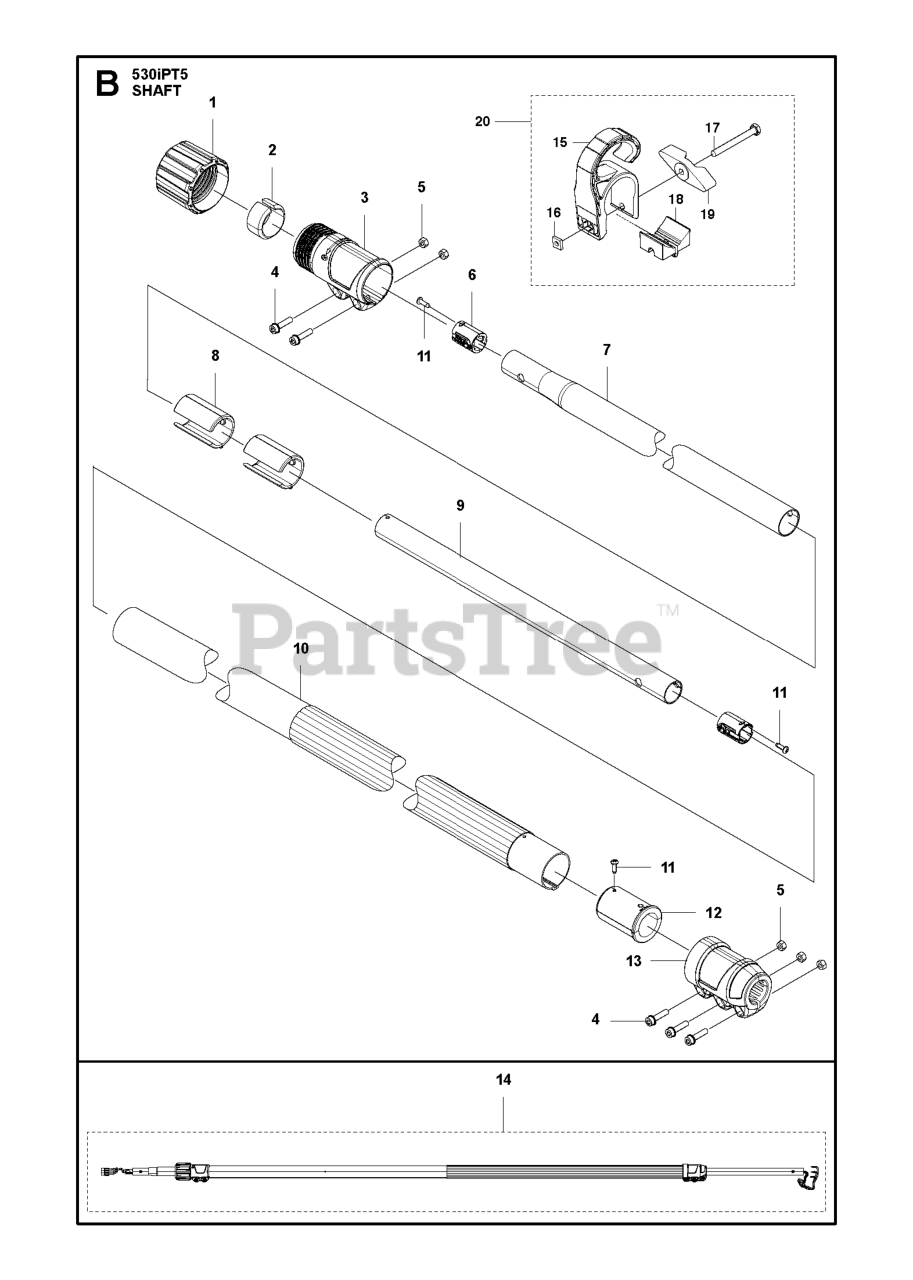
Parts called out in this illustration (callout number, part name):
3	CLAMPING SLEEVE
6	SPACER CABLELOCK
7	TUBE UPPER
8	GUIDE BUSHING
9	TUBE LOWER
10	TUBE ASSY LOWER
11	SCREW
13	CLAMPING SLEEVE
14	TUBE ASSY TELESCOPIC
17	SCREW M6X55
18	SPACING BLOCK
